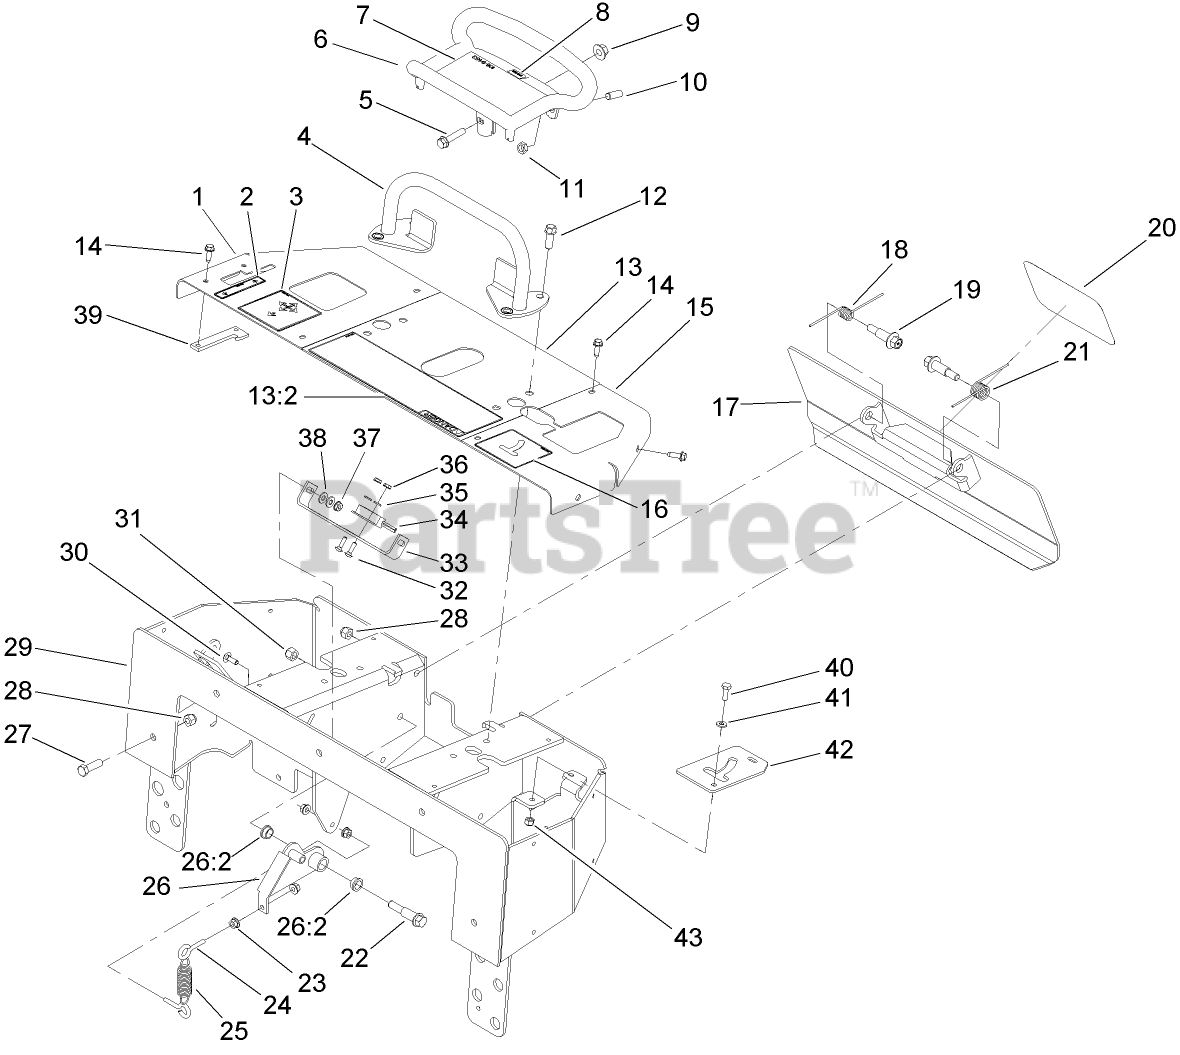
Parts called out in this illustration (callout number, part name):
1	PANEL-RH
2	DECAL-BRAKE
3	DECAL-LOADER
4	BAR-REFERENCE
5	SCREW-HHF
6	HANDLE-CONTROL
7	DECAL-TRACTION
8	DECAL
9	NUT-FLANGE
10	SCREW-SET
11	NUT-JAM
12	SCREW-TAPTITE
13	CENTER PANEL ASM
13:2	DECAL-DANGER
14	SCREW-HWH
15	PANEL-LH
16	DECAL-AUXILIARY
17	REVERSE PLATE ASM
18	SPRING-TORSION, LH
19	BOLT-SHOULDER
21	SPRING-TORSION, RH
22	BOLT-SHOULDER
23	NUT-HHF
24	BOLT-EYE
25	SPRING-EXTENSION
26	NEUTRAL CENTERING LEVER ASM
26:2	BUSHING-FLANGE
27	SCREW-HH
28	NUT-LOCK, NI
29	CONTROL PANEL ASM
30	BOLT-CARR
31	NUT-LOCK
32	SCREW-CARR
33	PLATE-SWITCH
34	SWITCH-PROXIMITY
35	WASHER-FLAT
36	NUT-KEPS
37	NUT-KEPS
38	WASHER-FLAT
39	PLATE-LOCKING, BRAKE
40	SCREW-HH
41	WASHER-FLAT
42	PLATE-STOP
43	NUT-LOCK, NI
